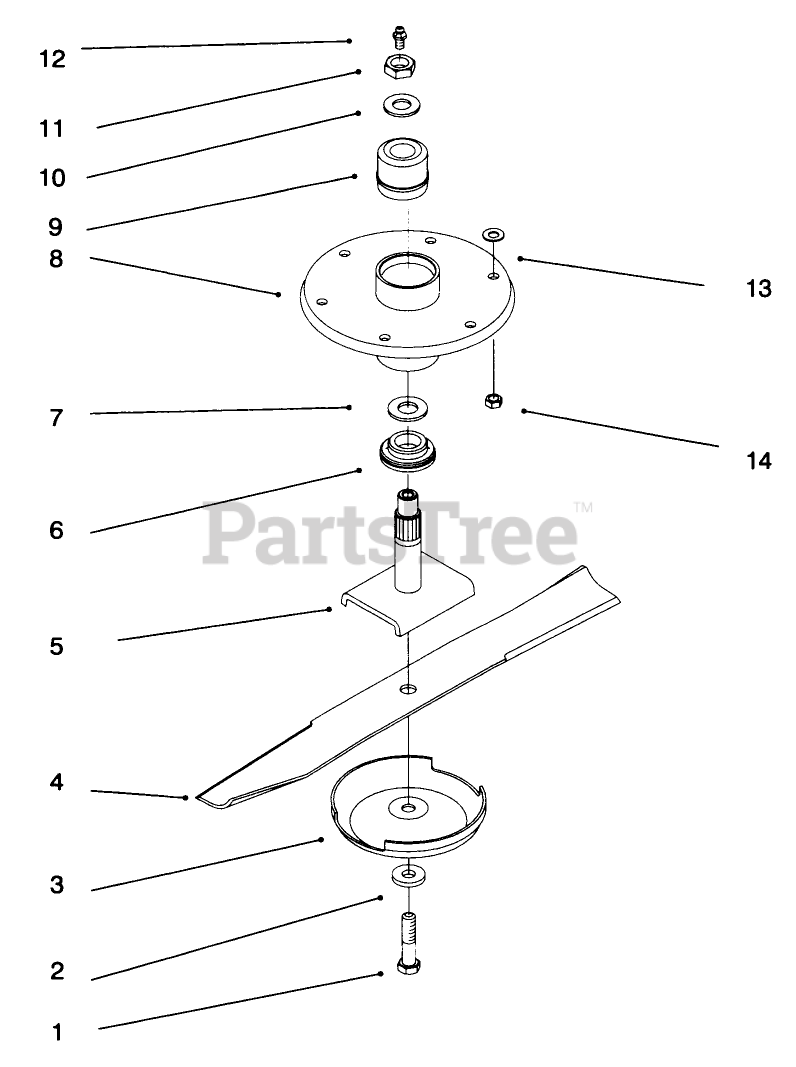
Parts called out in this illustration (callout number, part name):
1	SCREW-BLADE
2	WASHER
3	CUP-SCALP, ANTI
4	Blade
5	Shaft-Spindle
6	SPACER
7	SEAL-OIL
8	HOUSING-SPINDLE
9	BEARING ASM
10	WASHER
11	NUT-HEX
12	FITTING-GREASE
13	WASHER-FLAT
14	NUT-HF
